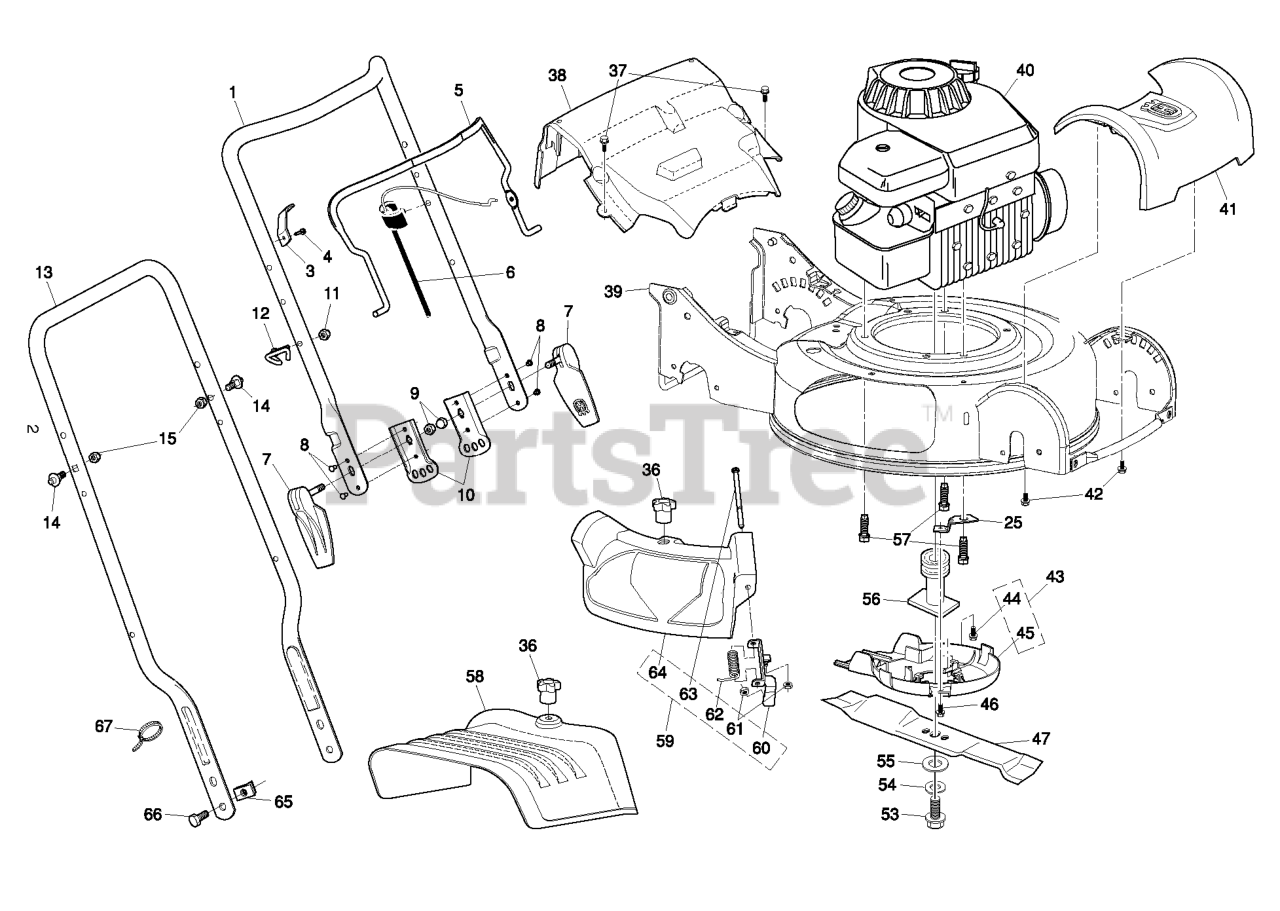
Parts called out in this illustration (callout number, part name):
1	HANDLE.ASM.UP.W/ADJ.BKT
5	BAIL CONTROL
6	CONTROL.ZONE.ASM
7	ASM.QUICK.RELEASE
9	Locknut, Hex 1/4-20
10	BRACKET.ADJ.3POS.GREY
11	NUT
12	RB GUIDE.ROPE.STD.BLK.ZIN WSL
14	STUD.QUICK.ADJUST
15	NUT.LOCK.5/16-18
25	BRACKET
36	KNOB.MULCH.DOOR
37	SCREW, HEX WASHER HEAD
42	SCREW.HWH.13-16-5.8.BZP
44	HINGE SCREW
46	SCREW.HEX.WSH
53	BOLT.HD.HEAD.3/8-24X2.50 (2 2)
54	LOCKWASHER
55	WASHER,HARDEN
57	BOLT 3/8-16X1-1/8
61	NUT.HEX.FLANGE.1/4
62	SPRING.MULCH.DOOR
63	ROD.HINGE.1/4"3.82"
64	WHEEL.8X1.75.MAG DR EXT WHITE
67	TIE GUIDE
